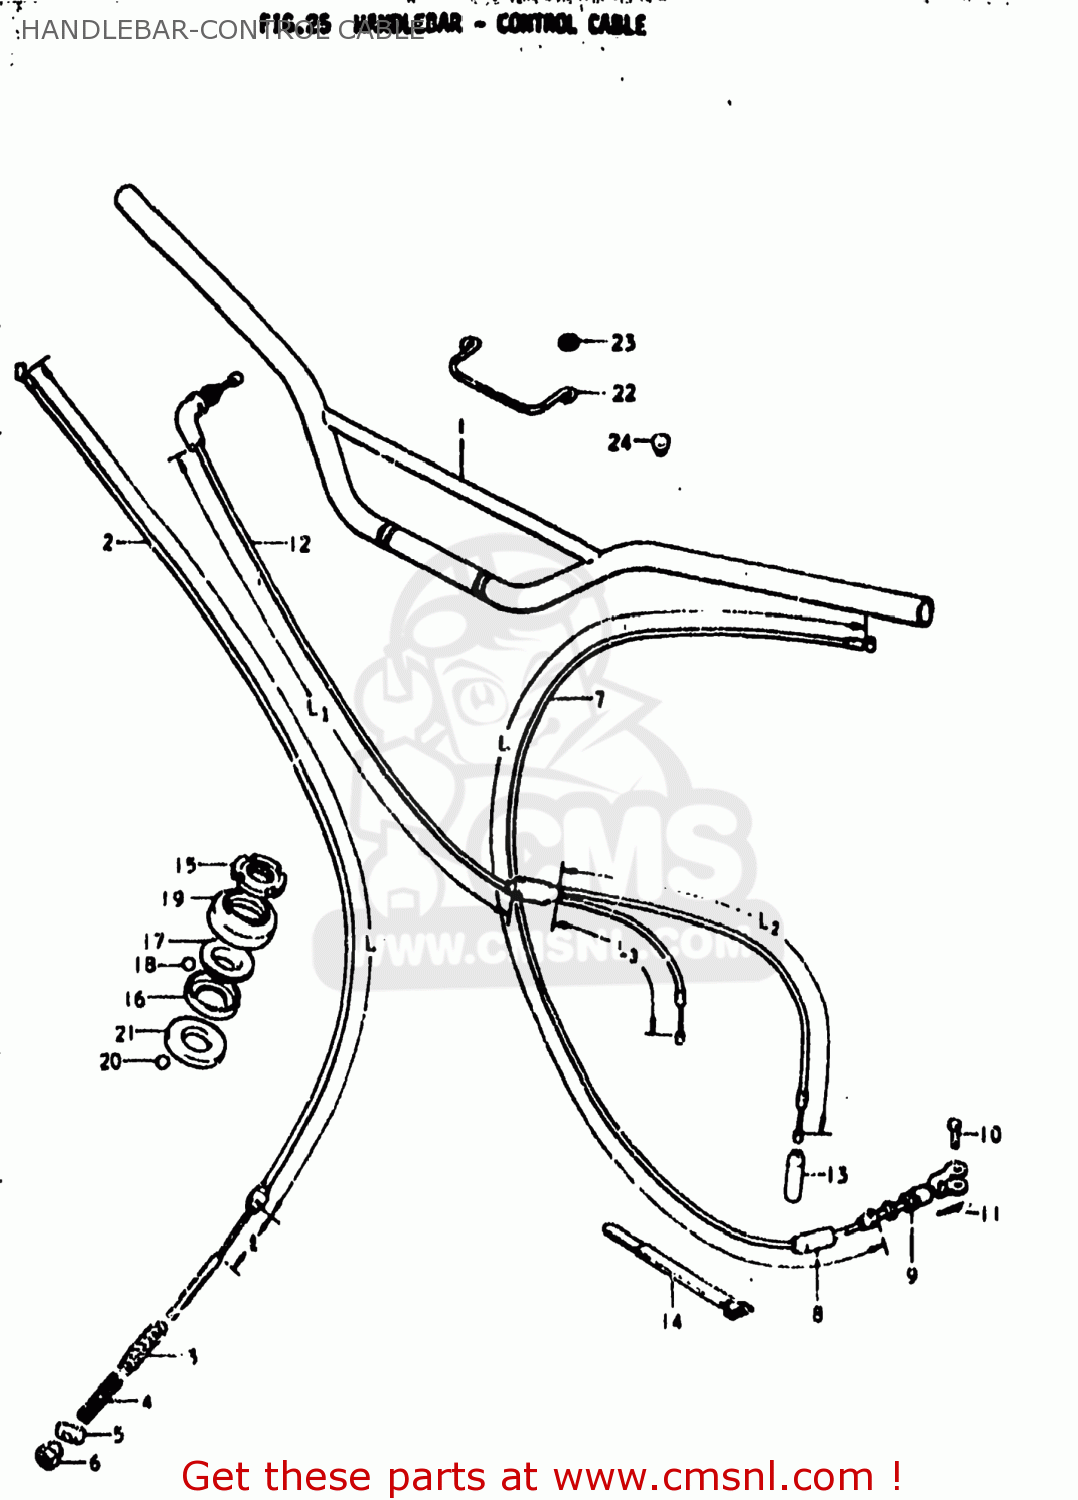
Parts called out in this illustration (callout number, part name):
1	HANDLEBAR
2	CABLE ASSEMBLY,FRONT BRAKE
3	SEAL,DUST(7X16X75)
4	SPRING
5	PIN,10X19
6	NUT
7	CABLE ASSEMBLY,CLUTCH
8	SEAL,DUST(7X18X30)
9	NUT
10	PIN(L:13)
11	PIN
12	CABLE ASSEMBLY,THROTTLE
13	SEAL,DUST(7X18X30)
14	CLAMP
15	NUT,STEERING STEM(25X44X10)
16	RACE,STEERING INNER UPR
17	RACE,STEERING OUTER UPR
18	BALL
19	DUST SEAL,STEERING UPR
20	BALL
21	LACE,STEERING INNER LWR
22	GUIDE,CABLE
23	WASHER
24	CAP
